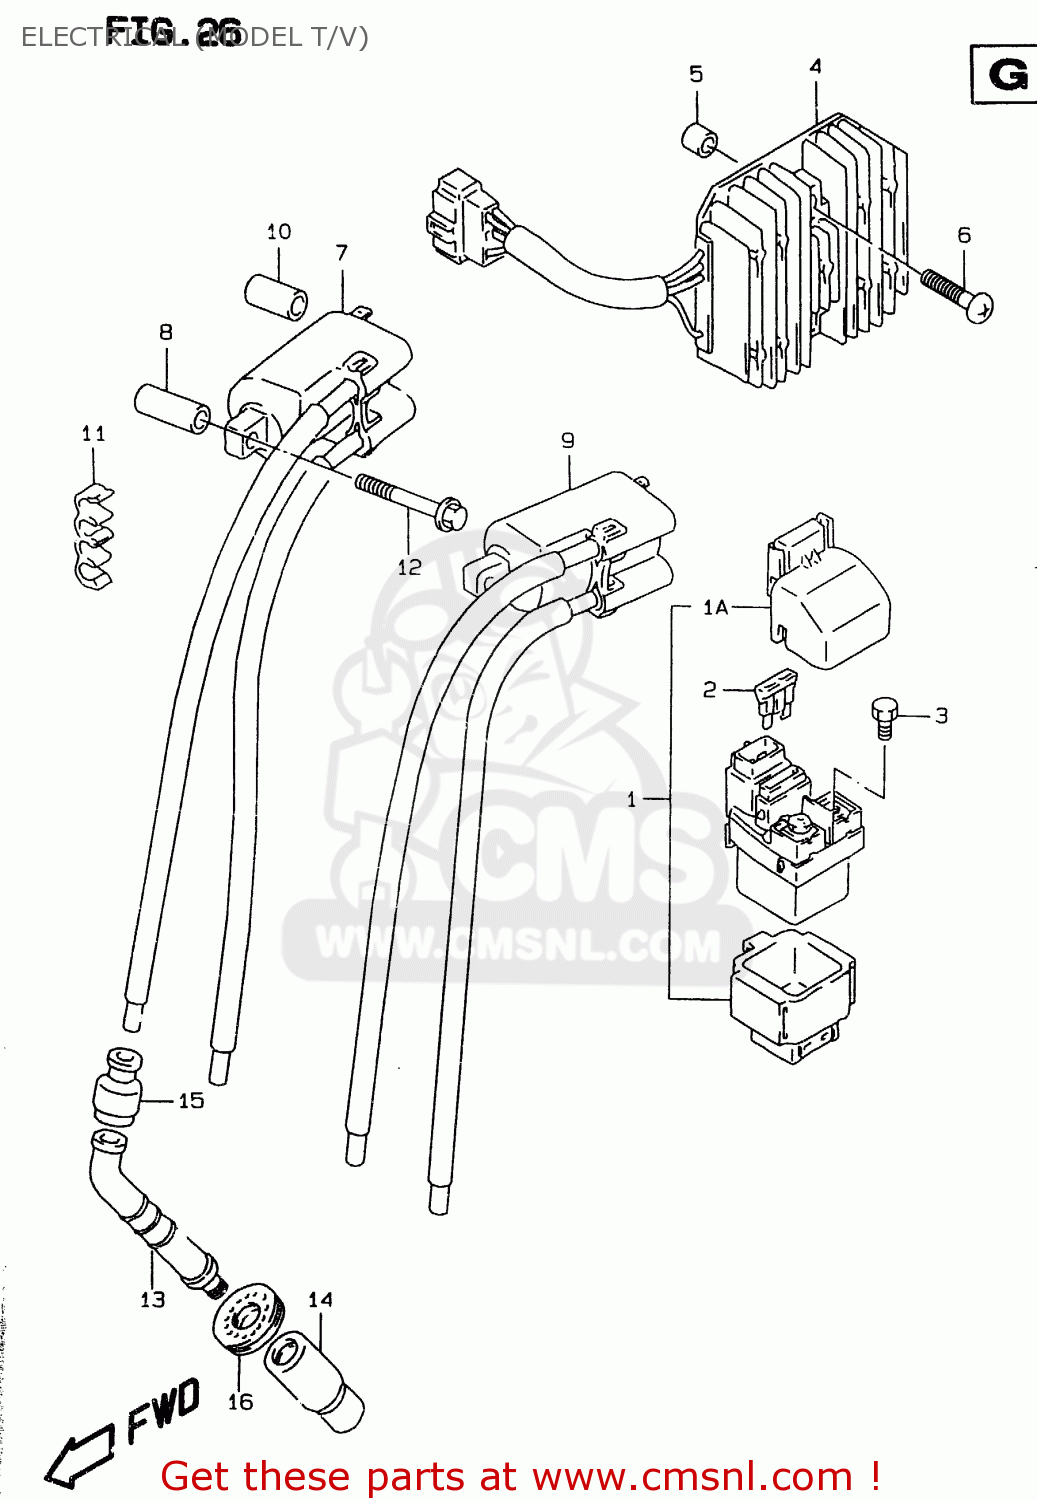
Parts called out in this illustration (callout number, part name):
1	RELAY ASSY,STARTING MOTOR
1A	COVER,STARTER RELAY
2	FUSE(30A)
3	SCREW(6X8)
4	RECTIFIER ASSEMBLY
5	SPACER(6.5X10X7)
6	SCREW
7	COIL ASSY,IGNITION
8	SPACER(6.5X10.5X25)
9	COIL ASSY,IGNITION
10	SPACER(6.4X10X28)
11	CLIP
12	BOLT
13	CAP ASSY,SPARK PLUG
14	SEAL,SPARK PLUG
15	SEAL,HIGH TENSION CORD
16	COVER,SPARK PLUG CAP
